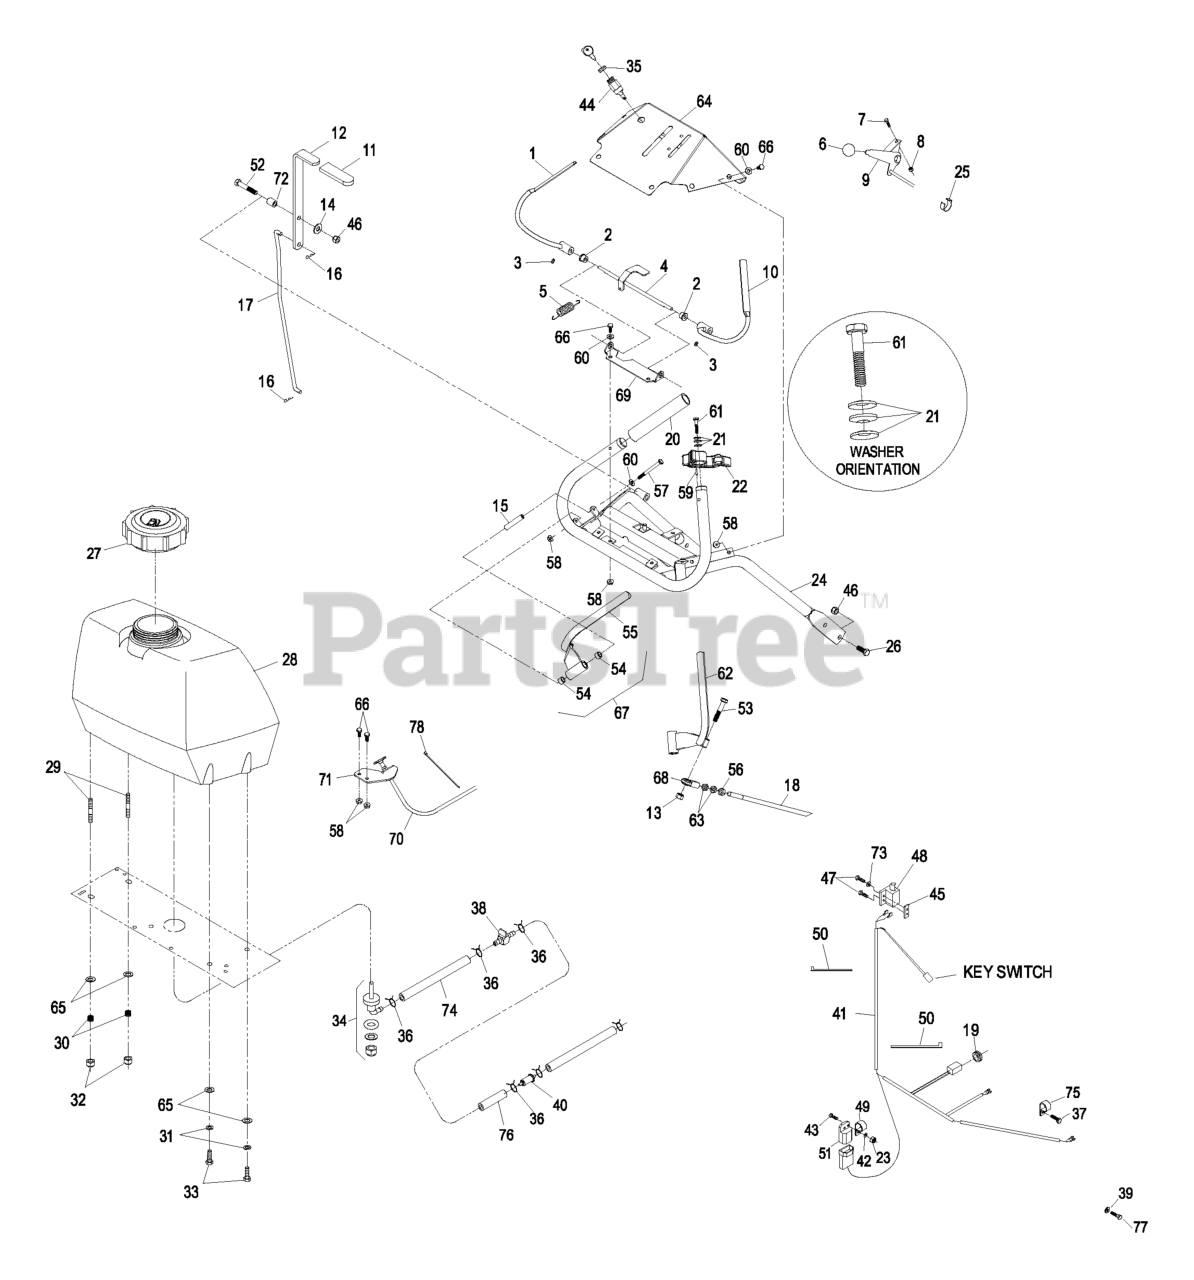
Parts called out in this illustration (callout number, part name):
2	BUSHING-NYLON
3	SCREW-SET
4	WLD,OPC LEVER AXLE
5	SPRING-EXTENSION
6	KNOB-BALL
7	BOLT-CARR
8	NUT-LOCK, NI
9	THROTTLE CABLE ASM
11	GRIP-LEVER
12	CLUTCH LEVER-W/GRIP
13	NUT-LOCK, NI
14	WASHER-FLAT
15	BUSHING-LEVER, DRIVE
16	PIN-COTTER
17	LINKAGE,UPPER BLADE (PLT)
18	LINKAGE,DRIVE (PLT)
19	GROMMET
20	GRIP-BAR, HANDLE
21	WASHER-SPRING
23	NUT-LOCK, NI
24	WLD,UPPER ECS HANDLE
25	CLIP-CABLE
26	SCREW-HH
27	CAP-FUEL, GAS
28	ASM,FUEL TANK W/B
29	STUD
30	SPRING-TANK, FUEL
31	WASHER-LOCK
32	NUT-LOCK, NI
33	SCREW-HH
34	FITTING-FUEL, BULKHEAD
35	NUT-SWITCH, IGNITION
37	SCREW-HH
38	VALVE-FUEL
39	WASHER-LOCK
40	Kawasaki Pn 41019-1055 W/6" Fuel Line
41	HARNESS-WIRING
42	WASHER-FLAT
43	SCREW-HH
44	SWITCH & KEY (INCLUDES NU
45	PLATE-TAPPED
46	NUT-LOCK, NI
47	SCREW-PPH
48	SWITCH-OPEN, NORMALLY
49	CLIP-LOOM
50	TIE-CABLE
51	MODULE-INTERLOCK
52	SCREW-CARR
53	SCREW-HH
54	BUSHING-SLEEVE
56	NUT-HEX
57	SCREW-HH
60	WASHER-FLAT
61	SCREW-HH
63	NUT-HJ
64	ASM,CONSOLE W/DECALS
65	WASHER-PLAIN
66	SCREW-HH
67	DRIVE LEVER-ASM, RH
68	JOINT-BALL, END
69	BRACKET,OPC AXLE
70	CABLE-CHOKE
71	BRACKET-CABLE, CHOKE
72	BUSHING-LEVER, LIFT
73	WASHER-FLAT
74	HOSE-FUEL
75	CLIP-LOOM
76	HOSE-FUEL
77	SCREW-HH
78	TIE-PLASTIC
